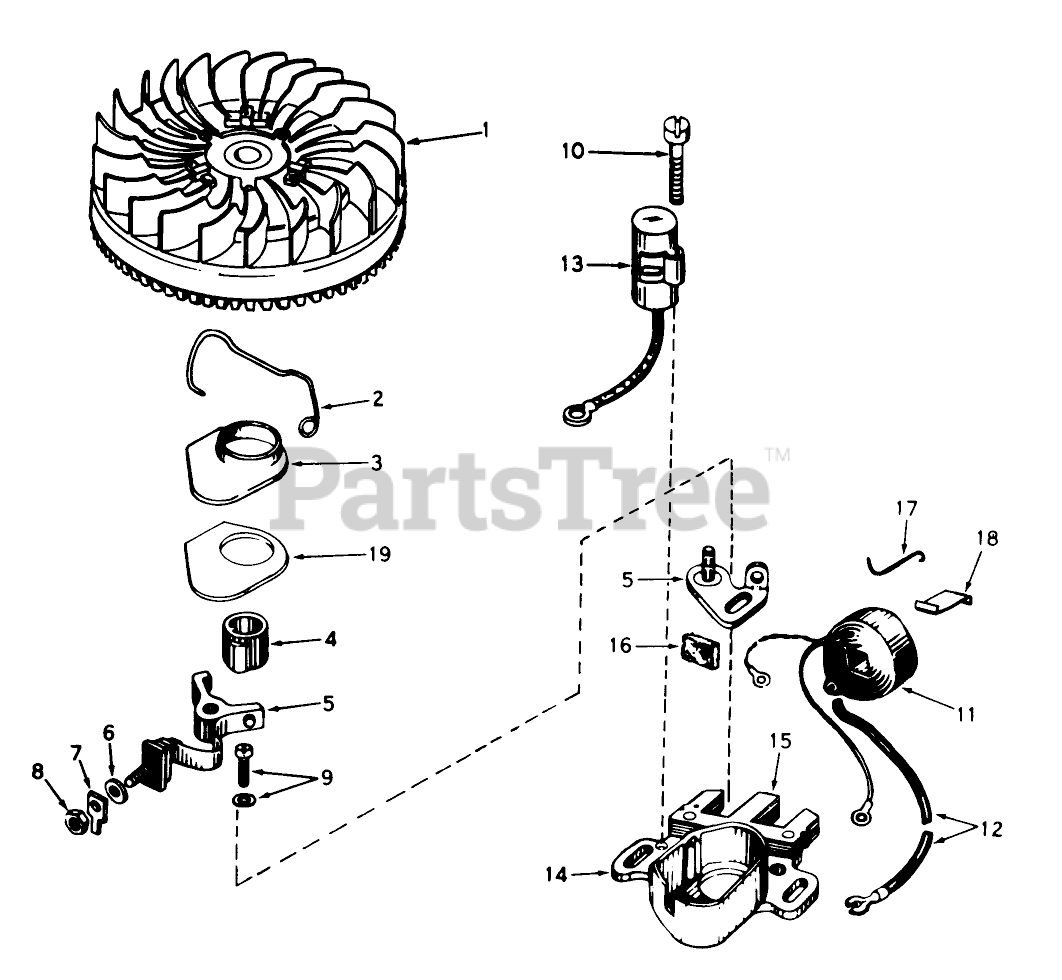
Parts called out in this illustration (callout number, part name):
1	FIywheel
2	Spring Breaker Box
3	Cover, Dust
4	Cam-Breaker
5	Breaker Assy.
6	Washer
7	Terminal, Ground
8	DECAL
9	Breaker Screw
10	Condenser Screw
11	Coil Assy. (Incl. No. 12)
12	Wire, Lead
13	Condenser
14	Core Plate
15	Stator Assy., (Incl. Nos. 2, 3, 5 thru 14 16 thru 19)
16	Felt,Cam Wiper
17	Clip, Coil
18	Spring Coil Wedge
19	Gasket Dust Cover
